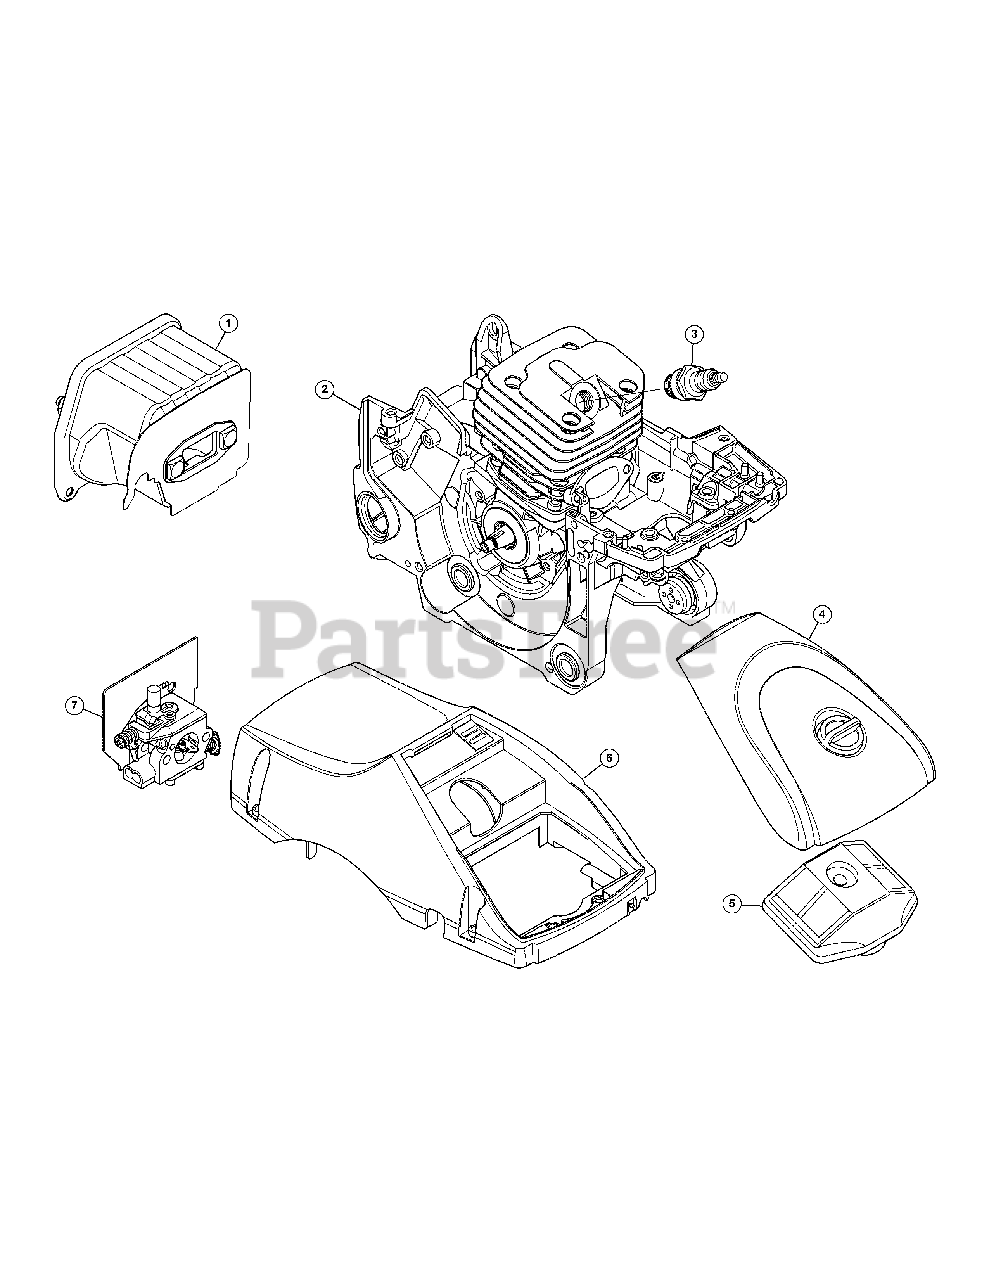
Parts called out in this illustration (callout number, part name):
1	Muffler Assembly
2	46cc Short Block Assembly
3	Spark Plug
4	Air Filter Cover Assembly
5	Air Filter
6	Cylinder Cover Assembly
7	Carburetor Assembly
